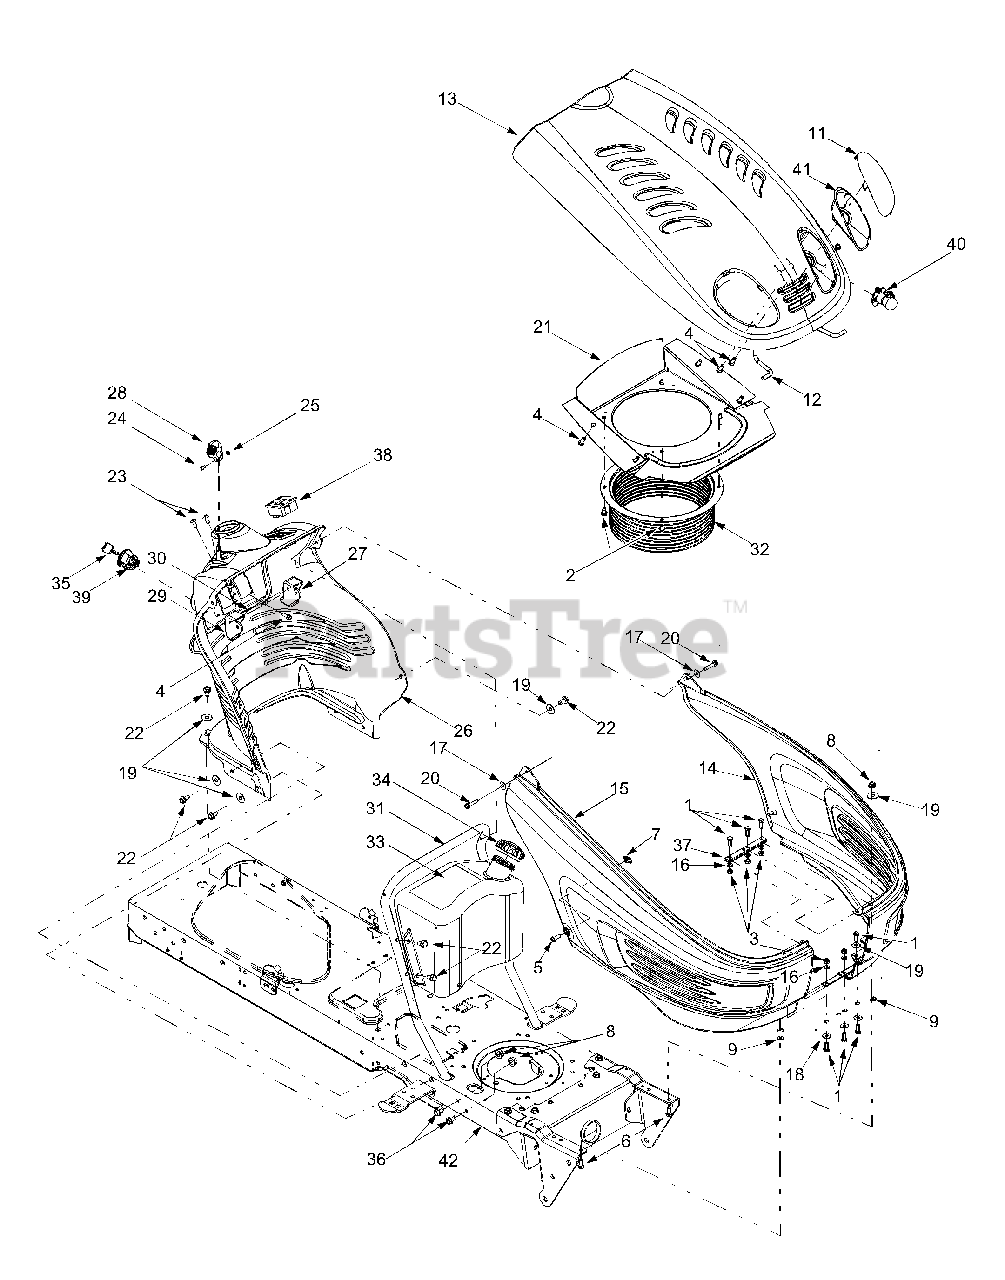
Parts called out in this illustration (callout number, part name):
1	Hex Cap Screw, 1/4-20 x .75
2	Self-tapping Screw, 1/4-20 x .5
3	Hex Nut, 1/4-20
4	Self-tapping Screw, 1/4-15 x .75
5	Pan Phillips Screw, 1/4-20 x .75
6	Hex Screw, 5/16-18 x 1.0
7	U-type Speed Nut, 1/4-20
8	Flange Lock Nut, 5/16-18
9	Speed Nut
11	RH Head Light Lens
12	Hood Support Rod
13	Hood
14	LH Side Panel
15	RH Side Panel
16	Lock Washer, 1/4
17	Flat Washer, .283 x .75 x .030
18	Flat Washer, .28 x .74 x .063
19	Flat Washer, .349 x 1.0 x .063
20	Self-tapping Screw, 1/4-20 x 0.75
22	AB Screw, 5/16-12 x .75
23	Self-tapping Screw, 1/4-20 x .50
24	Torx Screw, #8-32 x .375
25	Hex Nut, 8-32
26	Dash Panel, 4-style
27	Parking Brake Button
28	Throttle Control Lever
29	Cruise Control Button
30	Brake/Cruise Pivot Rod
33	Fuel Tank, 3-gallon
34	Fuel Cap
35	Ignition Key w/ plastic cover
36	TT Screw 5/16-18 x 0.875
39	Ignition Switch
40	Headlight Assembly
41	RH Headlight Reflector
